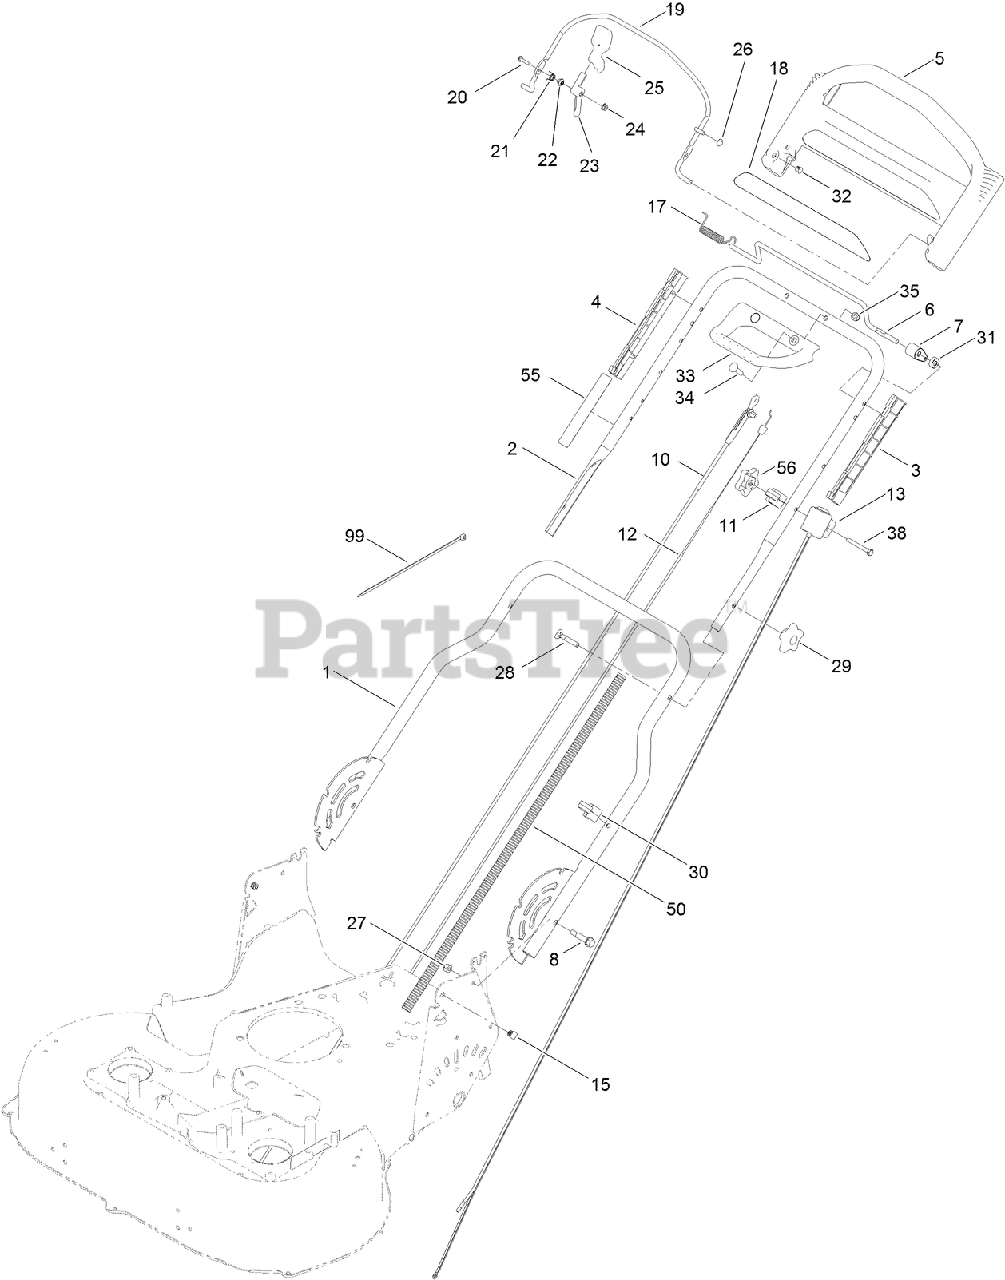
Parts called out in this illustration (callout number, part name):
1	HANDLE-LOWER
2	HANDLE-UPPER
3	GUIDE-LH
4	GUIDE-RH
5	HANDLE-CONTROL
7	LEVER-TRACTION
8	BOLT-SHOULDER, HHF
10	CABLE-BRAKE
12	CABLE-TRACTION
13	SWITCH HOUSING ASM
15	PLUG-SQUARE
18	DECAL-HANDLE
19	BAIL-BRAKE
20	SCREW-HWH
21	SPRING-TORSION
22	SPACER
23	LEVER
24	NUT-LOCK, FLANGE
26	NUT-SPEED
27	NUT-LOCK, NI
28	SCREW-HANDLE
29	KNOB-HANDLE
30	GUIDE-CABLE
31	SPACER
32	PLUG-DOME
33	HANDLE-ASSIST, TRACTION
34	BOLT-CARRIAGE
35	NUT-ACORN
38	SCREW-HH
50	CONDUIT-CONVOLUTED
55	DECAL-TRACTION, ADJUST
56	KNOB-HANDLE, LOCKING
99	TIE-CABLE
